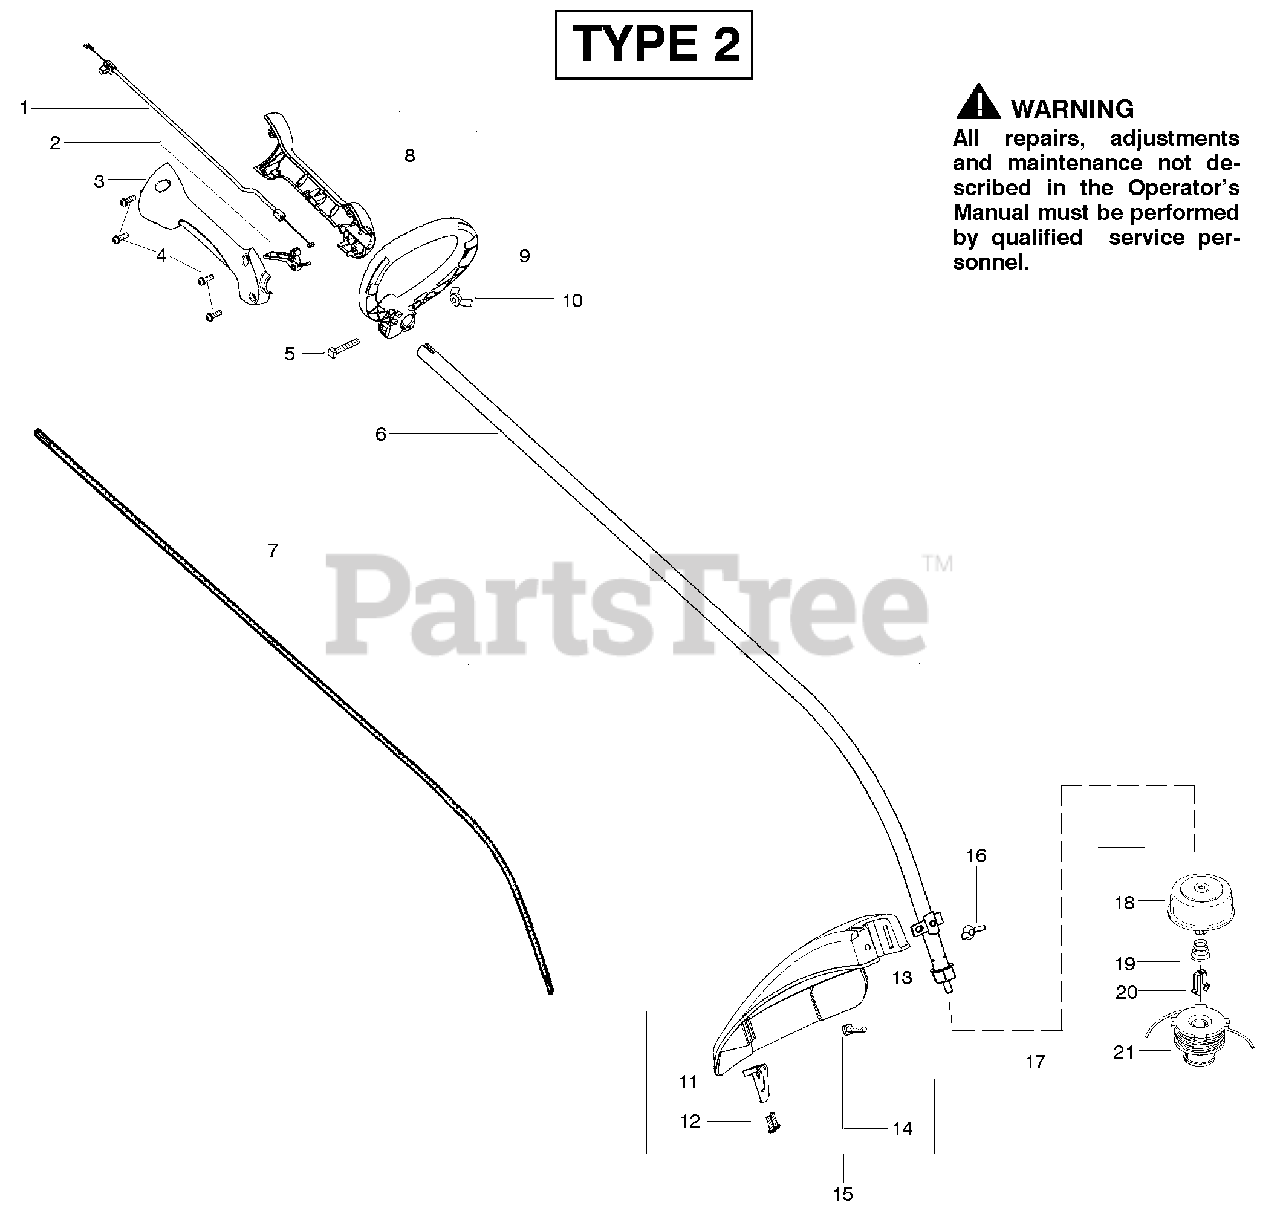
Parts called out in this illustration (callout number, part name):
1	Assy-Throttle Cable
3	Throttle Hsg. (Right)
4	Screw-Throttle Hsg.
5	Bolt-Handle/Shield
6	Kit-Drive Shaft Hsg.
7	Shaft- Flex
8	Throttle Hsg. (Left)
9	Handle-Assist
10	Wingnut
11	Line Limiter
12	Screw-Line Limiter
13	Dust Cup
15	Kit-Shield Assy
16	Wingnut
17	Accy-TNG VI Cutting Head
18	Assy-Hub
19	Spring-Compression
20	Clip-Retainer-Head
21	Accy- Spool w/Line
